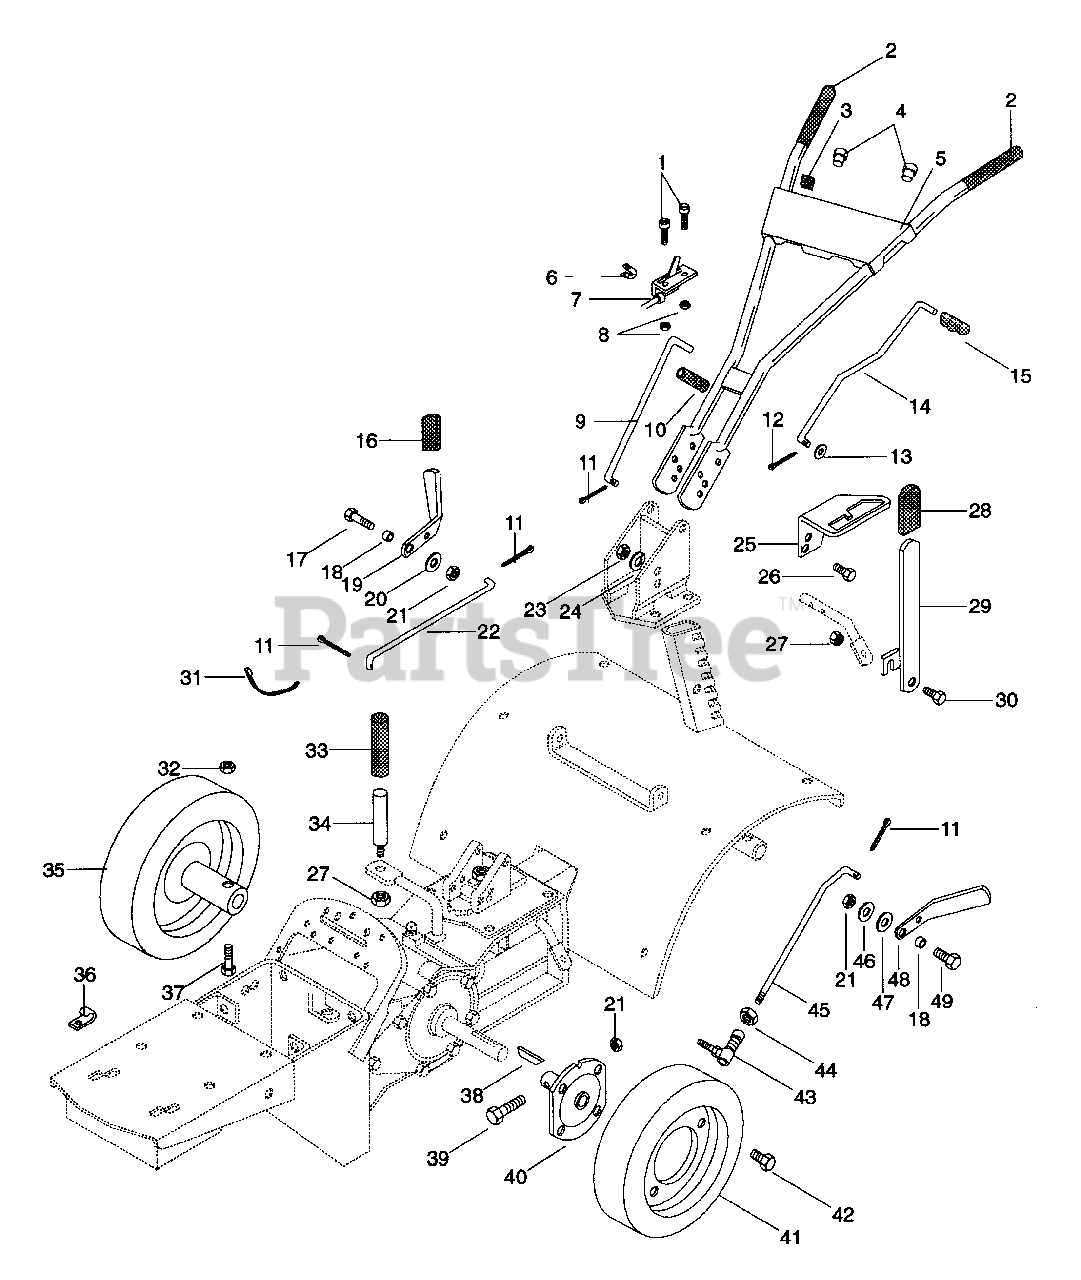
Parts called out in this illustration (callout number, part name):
1	SCR-MCH 10-24X.50 SLRH PL
2	HANDLEGRIP
3	KNOB, CONTROL-THROTTLE
4	SNAP BUSHING
5	HANDLE BAR
6	CABLE RETAINER
7	THROTTLE CONTROL
8	NUT-KEPS 10-24 PL
9	POSITION ROD
10	GRIP - 5/16 ID X 2 7/8 - BLACK
11	PIN-COTR .09X.75 PL
12	PIN-COTR .12X1.0 PL
13	WSHR-FL-STL.344X.688X.065PL
14	CLUTCH ROD
15	GRIP - 3/8 ID X 2 7/8 - BLACK
16	GRIP
17	BLT-HEX .31-18X1.25 PL GR2
18	SPACER BUSHING .5 X .32 X .21
19	DRIVE CLUTCH HANDLE
20	WSHR-FL-STL .38X.875X.083 PL
21	NUT-LK .312-18 GR A PL
22	DRIVE CLUTCH ROD
23	NUT-HEX .375-16
24	WSHR-LK .375X.115 HVY PL
25	QUADRANT
26	BLT-HEX .38-16X1.00 PL
27	NUT-FLG. .312-18 PL
28	GRIP
29	ENGAGING ARM
30	BLT-HEX .31-18X.63 PL GR 2
31	TIE DOWN
32	NUT-LK .437-14 GR A PL
33	GRIP - 1/2 ID X 4 1/2 - BLACK
34	CLUTCH ARM
35	WHL
36	CLIP
37	BLT-HEX .44-14X2.00 PL GR2
38	KEY-FTHR .25X1.875X.25 SAE
39	BLT-HEX .31-18X2.00 PL GR2
40	WHEEL HUB
41	T/WHL ASSY
42	SCR-TAP .500-20X.62 HH PL
43	SNAP IN BALL JOINT
44	NUT-HEX .312-24 PL
45	TILLER CLUTCH ROD
46	WSHR-FL-STL .344X1.375X.075 PL
47	SPACER .344X1.000X.375
48	TILLER CLUTCH HANDLE
49	BLT-HEX .31-18X.75 PL GR2
